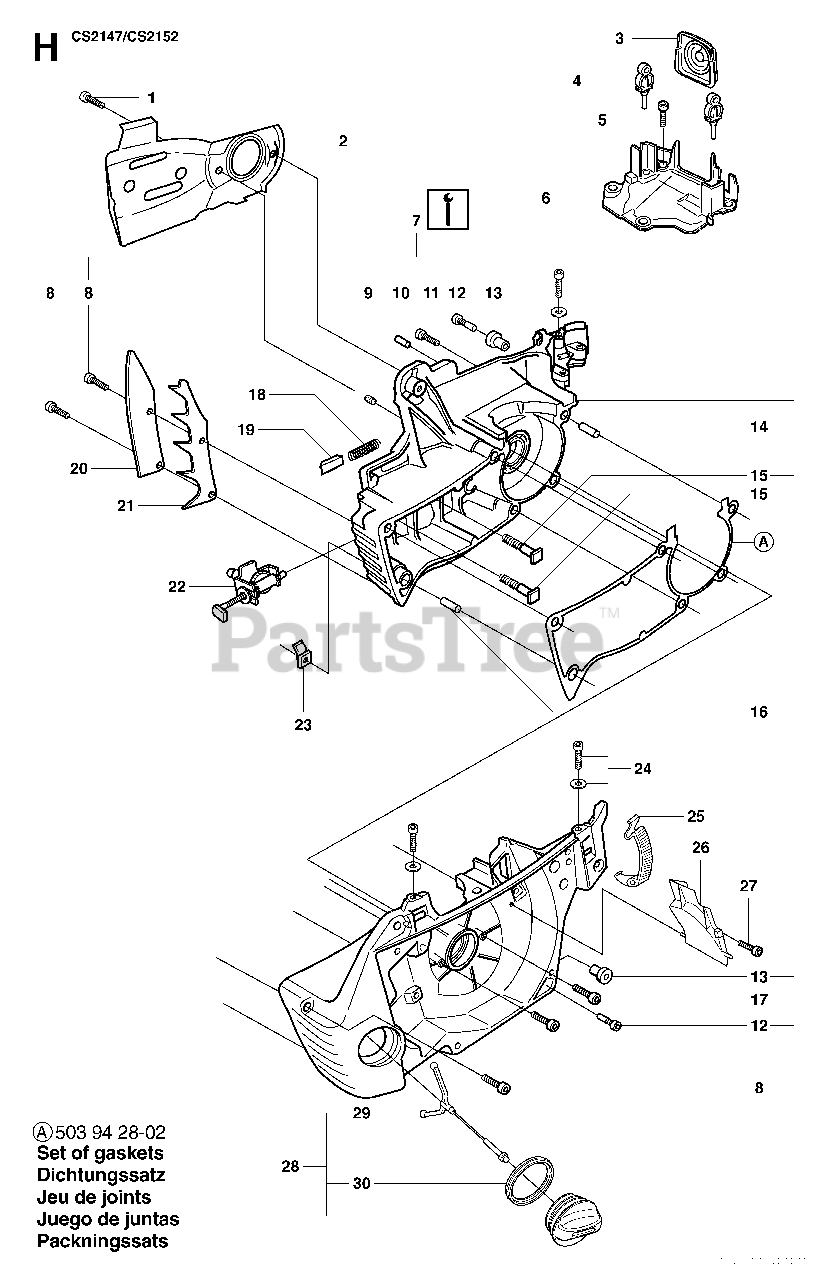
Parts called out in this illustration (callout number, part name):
7	CRANKCASE ASSY.
13	MOVEMENT LIMITER
18	LOCK SPRING
21	FELLING DOG
22	CHAIN TENSIONER
23	CHAIN CATCHER
26	DEFLECTOR
30	OILCAP GASKET
A	GASKET SET
